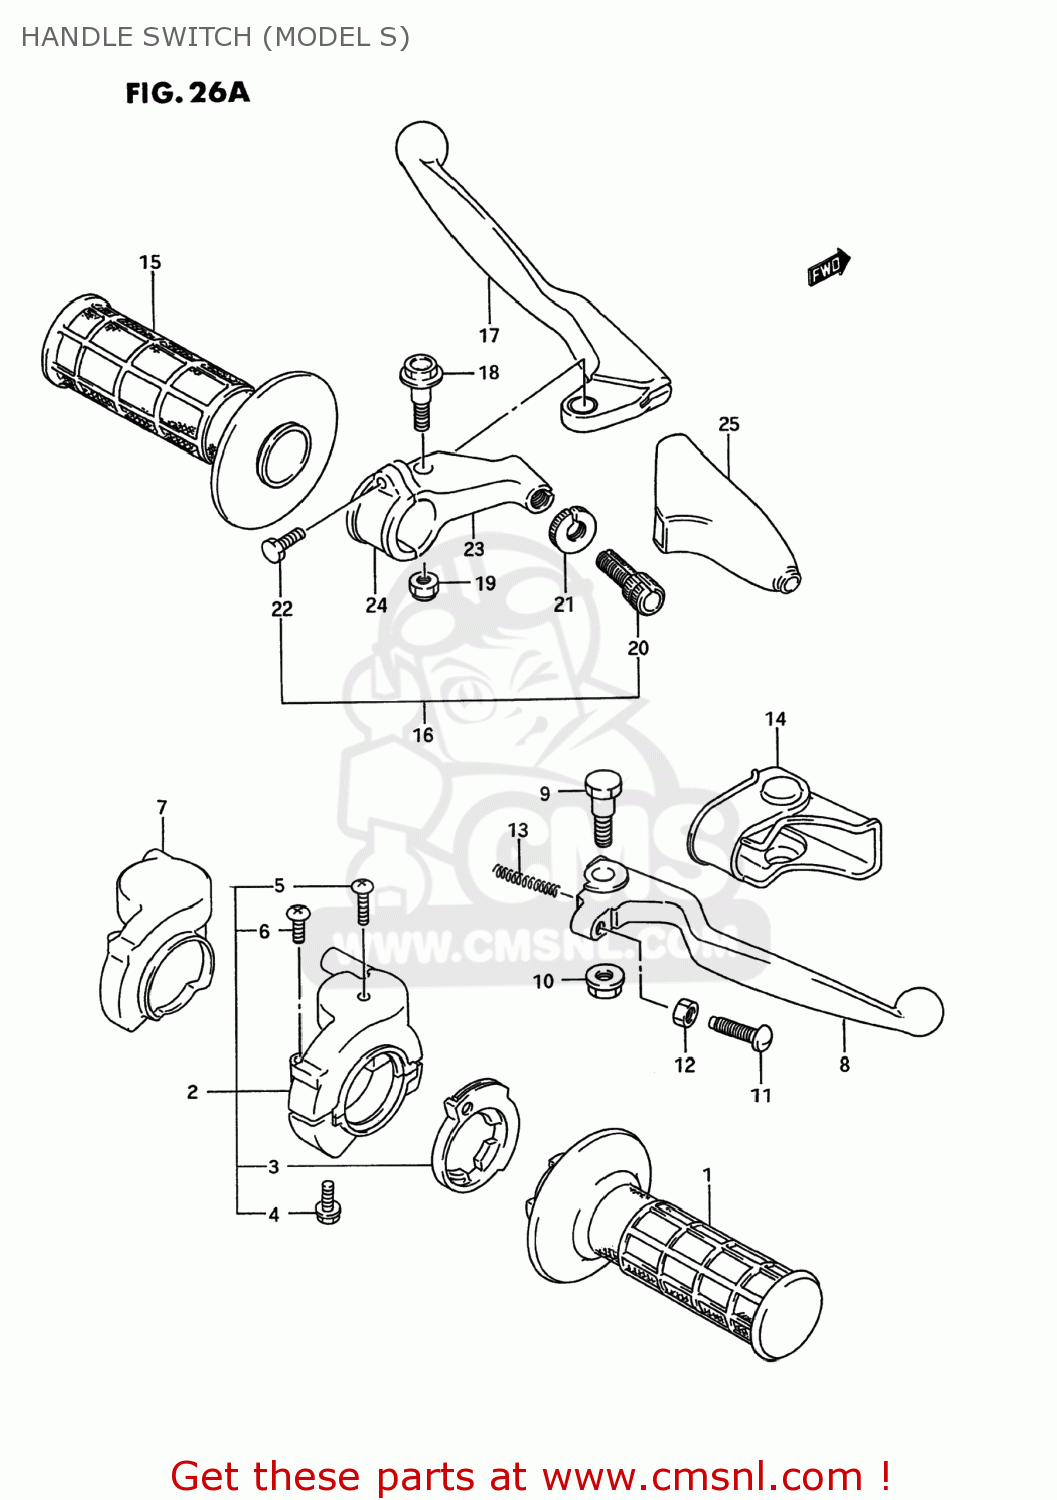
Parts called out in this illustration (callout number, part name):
1	GRIP,THROTTLE
2	CASE ASSEMBLY,THROTTLE
3	ROTOR,THROTTLE
4	BOLT 6X25
5	SCREW,UPPER
6	SCREW
7	COVER,THROTTLE CASE
8	LEVER,BRAKE
9	BOLT,BRAKE LEVER
10	NUT,BRAKE LEVER
11	BOLT,ADJUST
12	NUT ,5MM
13	SPRING,RETURN
14	COVER,BRAKE LEVER
15	GRIP,L
16	LEVER ASSEMBLY,CLUTCH
17	LEVER,CLUTCH
18	BOLT,LEVER
19	NUT 6MM
20	ADJUSTER,WIRE
21	NUT,LOCK
22	BOLT
23	HOLDER,CLUTCH LEVER
24	BRACKET,CLUTCH LEVER HOLDER
25	COVER,CLUTCH LEVER
